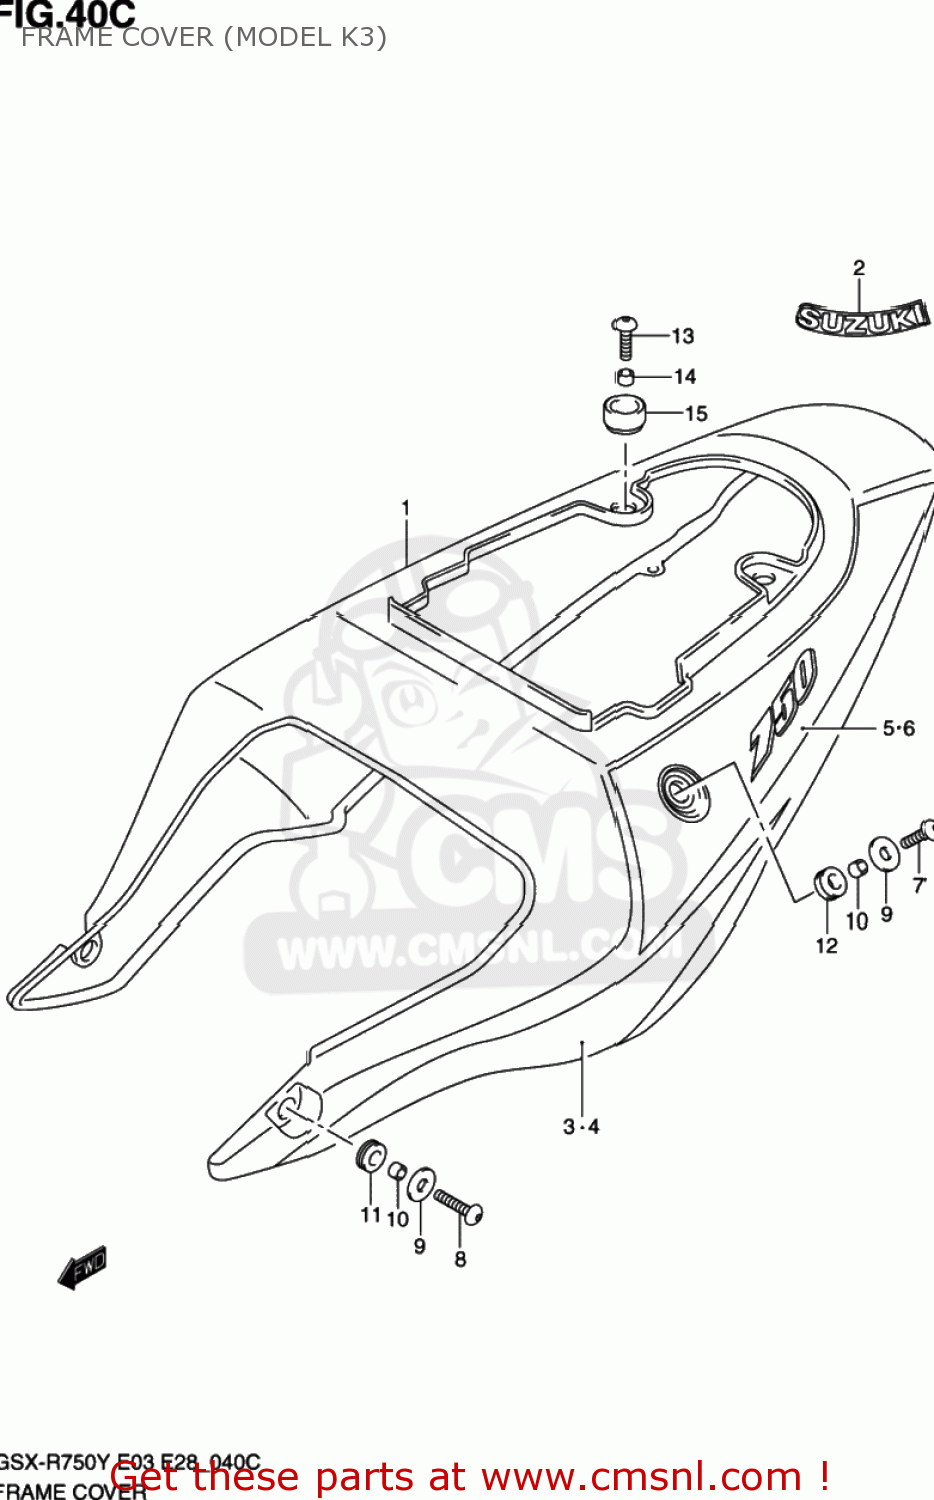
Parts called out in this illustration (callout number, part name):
1	COVER ASSY,FRAME(BLACK)
2	EMBLEM,SUZUKI
3	TAPE,FRAME COVER FR,R
4	TAPE,FRAME COVER FR,L
5	TAPE,FRAME COVER UPR,R
6	TAPE,FRAME COVER UPR,L
7	SCREW(6X25)
8	SCREW(6X30)
9	WASHER(6.5X20X2)
10	SPACER(6.5X10X7)
11	CUSHION,FRAME COVER FR
12	CUSHION,FRAME COVER SIDE
13	SCREW(6X25)
14	SPACER(6.5X10X9.4)
15	CUSHION
